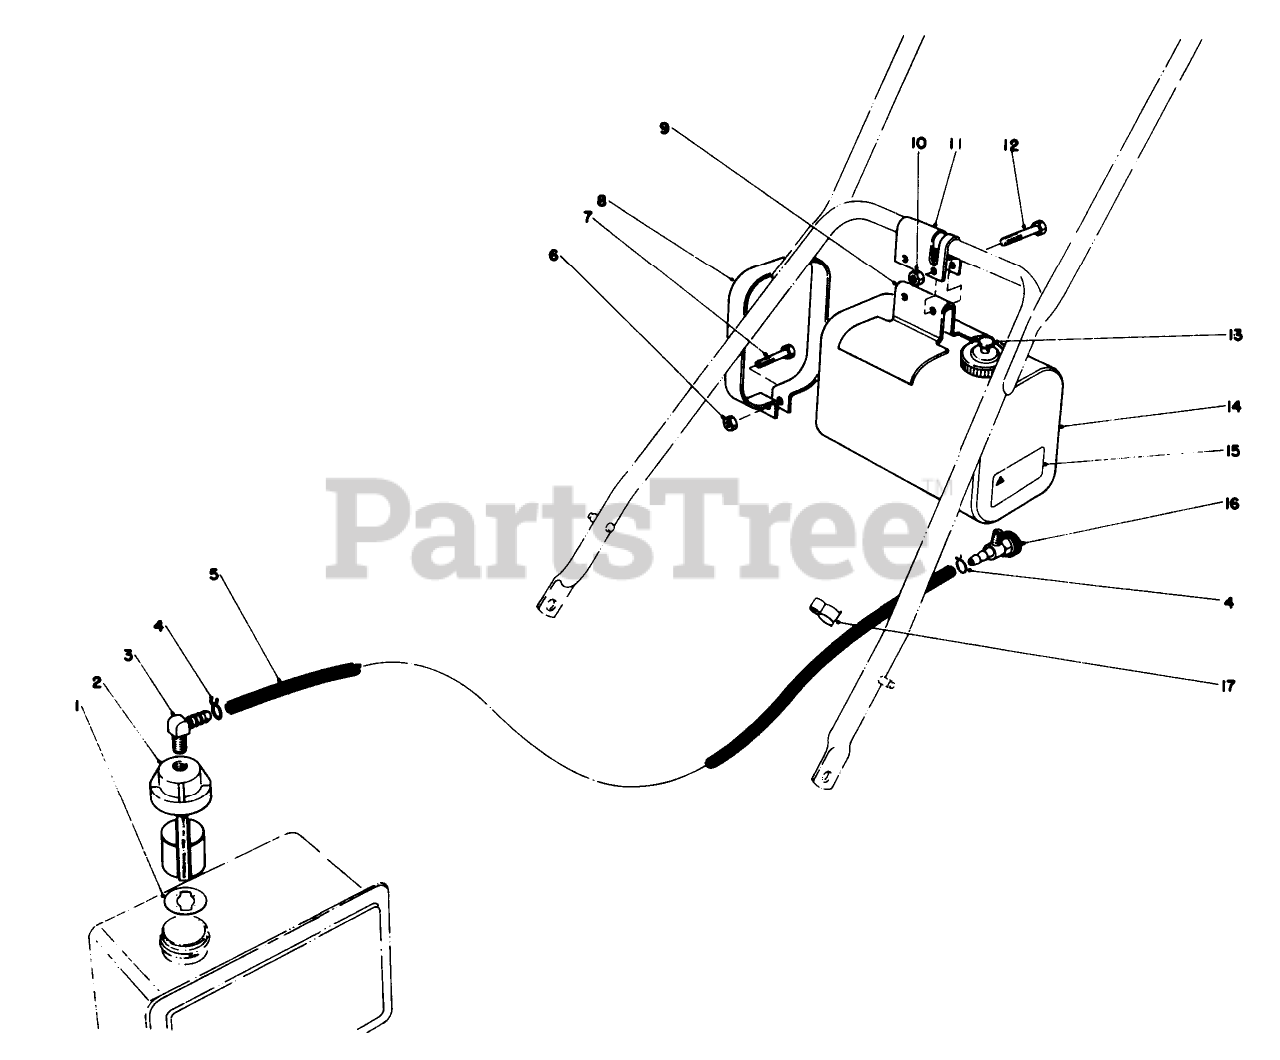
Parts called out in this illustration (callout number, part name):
2	FUEL CONT VALVE ASM
3	CONNECTOR-HOSE
7	SCREW-HH
12	SCREW-HH
